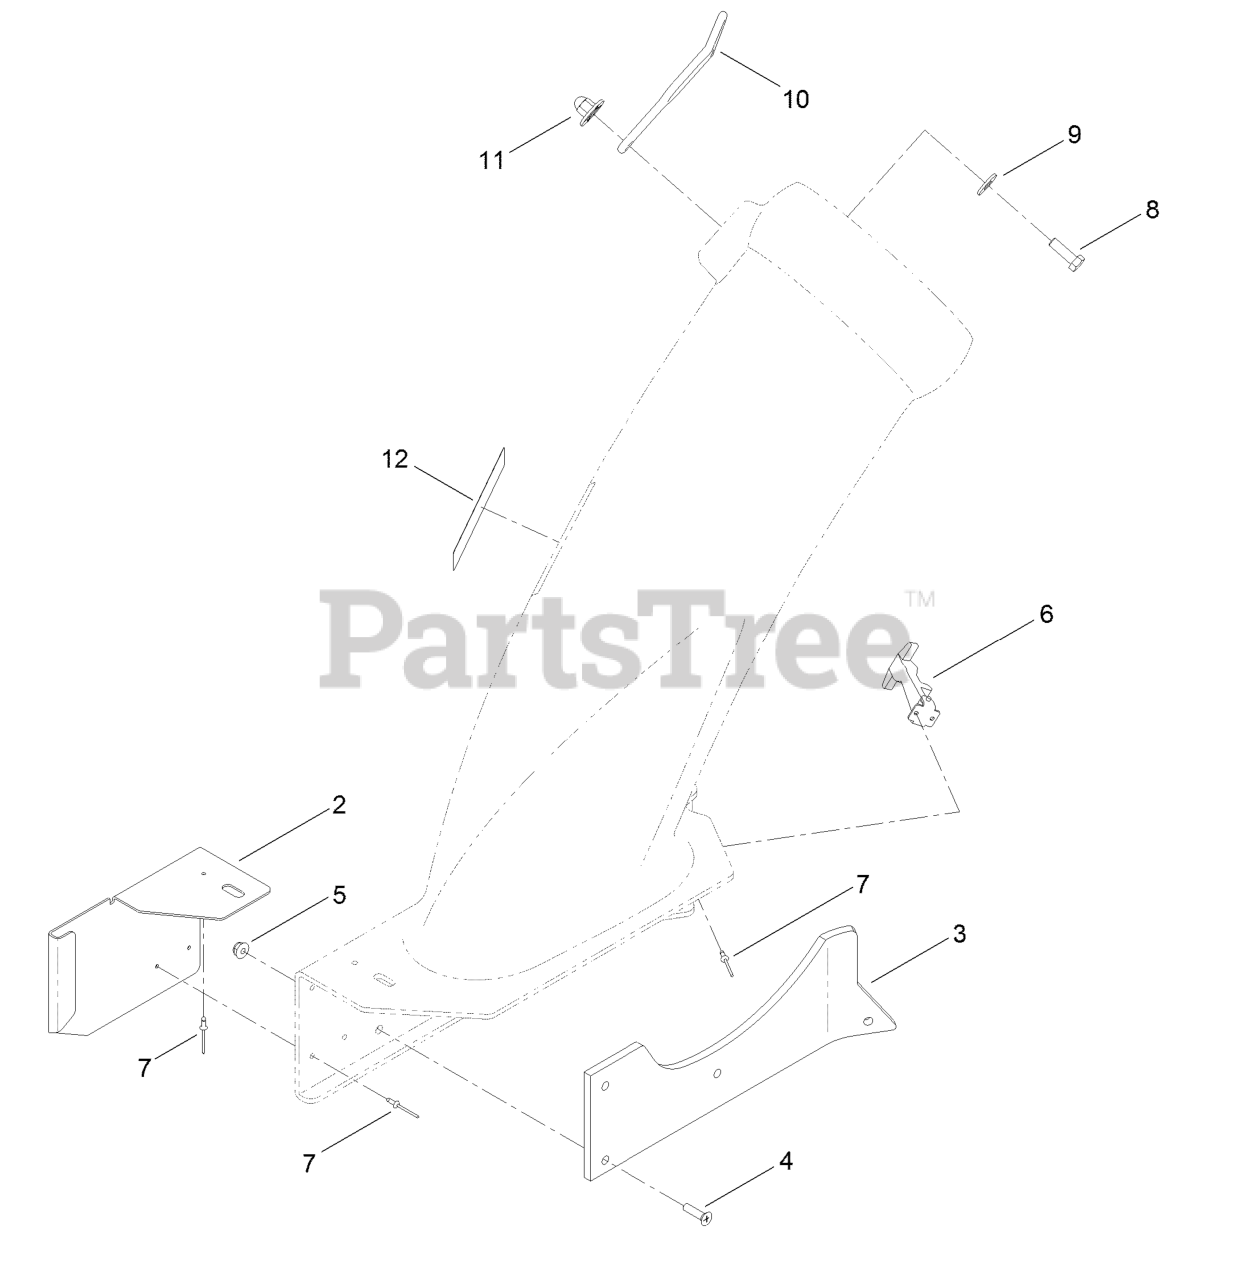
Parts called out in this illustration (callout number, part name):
2	PLATE-BAGGER
3	PLATE-SPACER
4	SCREW-FH
6	HANDLE ASM
7	RIVET-POP
8	SCREW-HH
9	WASHER-FLAT
10	RETAINER-DUCT
11	NUT-IMPELLER
12	DECAL-DANGER
